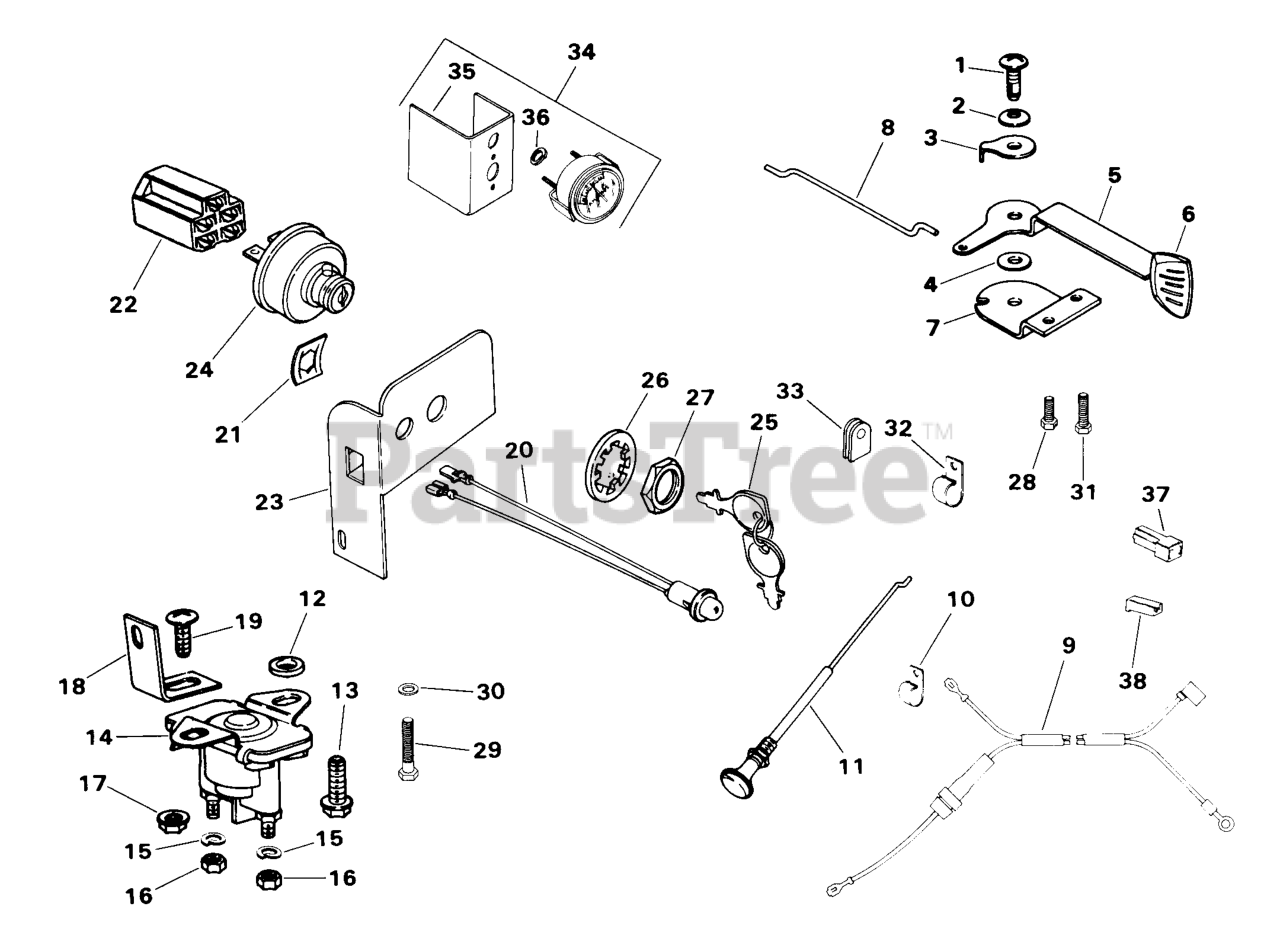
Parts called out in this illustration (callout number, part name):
9	HARNESS, WIRING - DISCONTINUED
13	SCREW, WSH HD TAP 1/4-20X3/4" USE 25 086 100-S
14	SOLENOID - USE 25 435 02
15	WASHER, SPRING LOCK 1/4"
16	NUT, 1/4-20 GRADE 2 USE 25 100 20-S
17	PALNUT, 1/4-20
18	BRACKET - DISCONTINUED
22	CONNECTOR
24	SWITCH ASSY, KEY (KM)-USE 25 099 32-S
25	KEY, SET -USE 48 340 01-S
26	WASHER, INTERNAL TOOTH
27	NUT, KEY SWITCH
37	CONNECTOR
38	CONNECTOR
